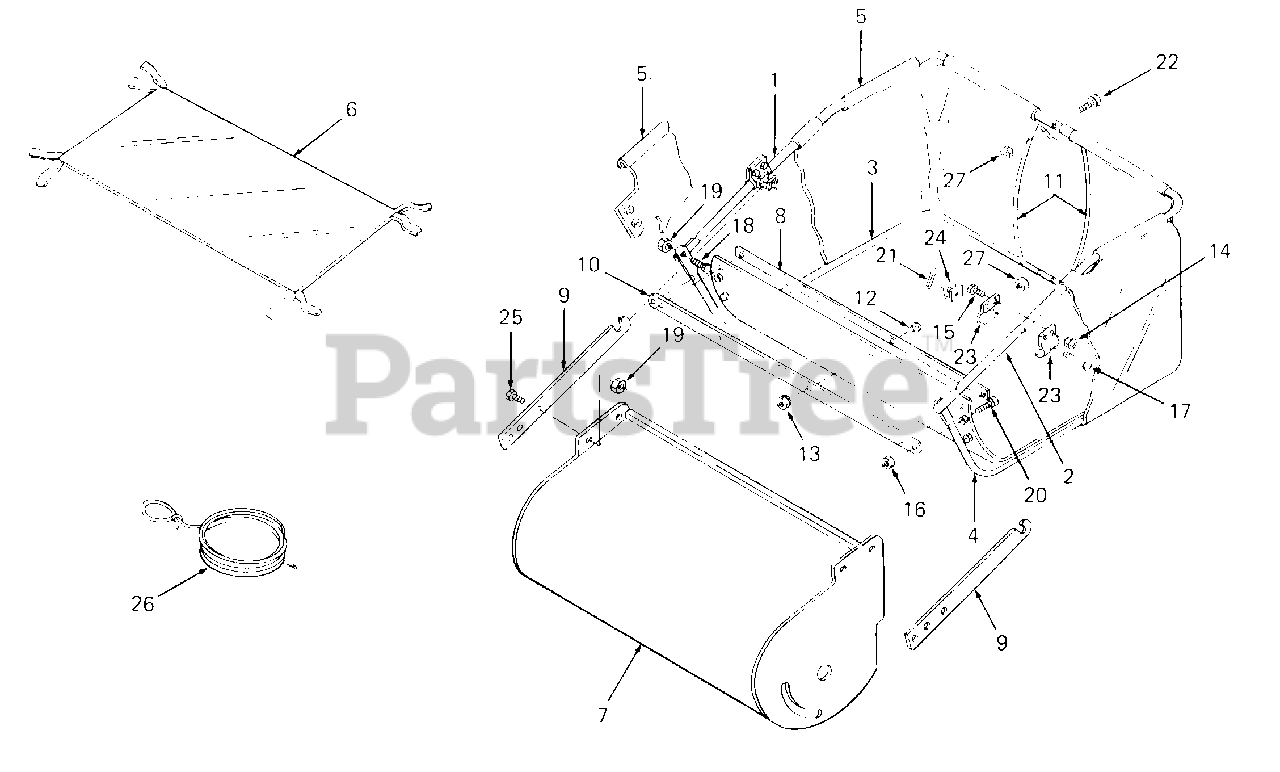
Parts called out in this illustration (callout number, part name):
1	Tube, Upper Hopper RH
2	Tube, Upper Hopper LH
3	Tube, Lower Hopper RH
4	Tube, Lower Hopper LH
5	Bag, Hopper
6	Screen, Wind, 38
9	Arm, Bag Mount
10	Strap, Bag Frame
11	Rod, Hopper Support
12	Screw, Truss Hd, Slotted #10-32 x 5/8 Lg
13	Nut, Hex Lock, #10-32 Thd
14	Nut, Hex Lock, 5/16-18 Thd
15	Bolt, Hex, 5/16-18 x 3/4 Lg
16	Nut, Hex Lock, 1/4-20 Thd
17	Pin, Clevis, 3/8 Dia x 3"
18	Bolt, Hex, 3/8-16 x 3/4 Lg
19	Nut, Hex Lock, 3/8-16 Thd
20	Bolt, Hex, 1/4-20 x 1.25 Lg
21	Pin, Cotter, 1/8 Dia x 3/4 Lg
22	Bolt, Curved Head, 1/4-20 x 1.0 Lg
23	Clamp, Hopper Mount
24	Clevis, Bag Retainer
25	Bolt, Hex, 3/8-16 x 1-1/4 Lg
26	Rope, Hopper
27	Nut, Hex Lock, 1/4-20 Thd
